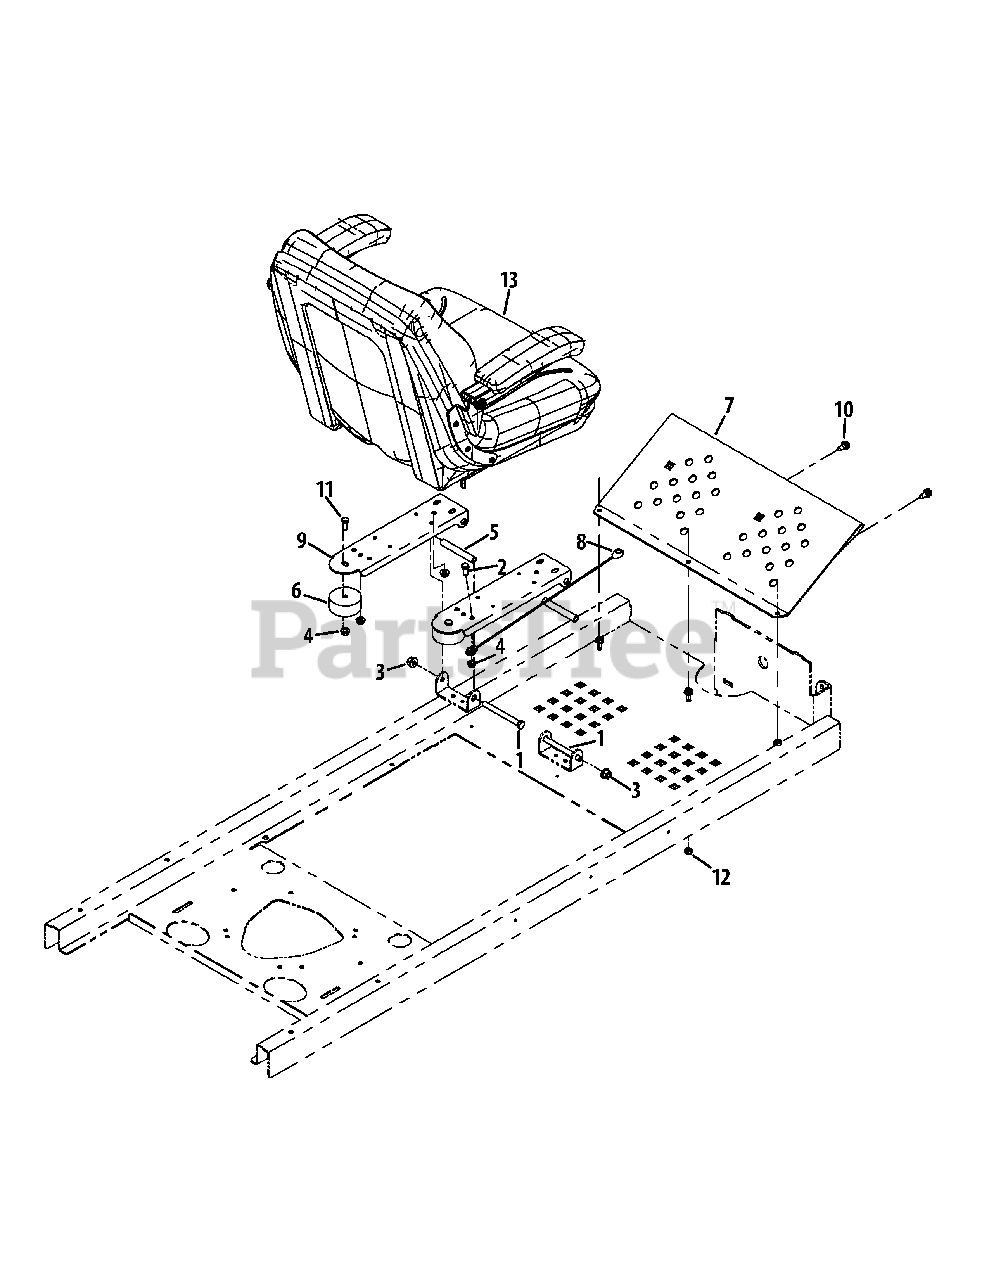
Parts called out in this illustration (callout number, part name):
1	Hex Cap Screw, 3/8-16 x 4.00
2	Hex Cap Screw, 5/16-18 x 3/4
3	Flange Lock Nut, 3/8-16
4	Flange Lock Nut, 5/16-18
5	Spacer, .370 ID x .500 x 3.45
6	Bumper, 2.50 x 1.13
7	Foot Rest Bracket
8	Lift Cable
9	Seat Mounting Bracket
10	Self Tapping Screw 5/16-18 x .750
11	Hex Cap Screw, 5/16-18 x .75
12	Nylock Nut, 5/16-18
